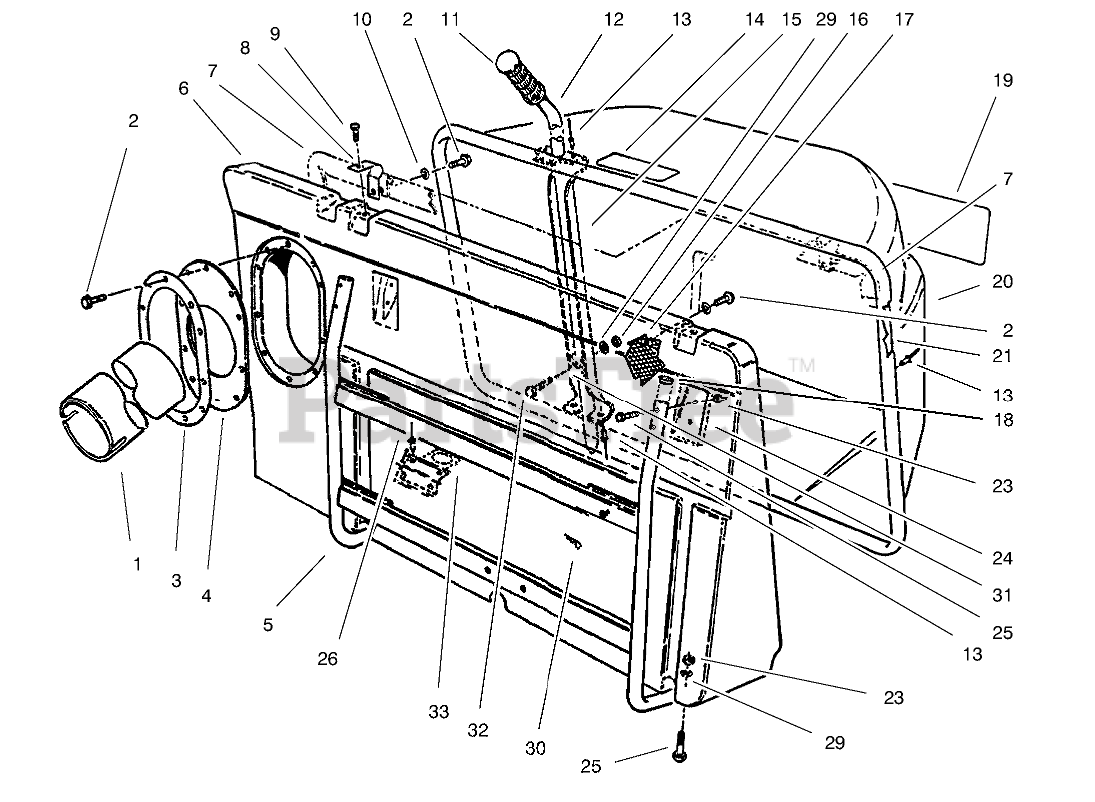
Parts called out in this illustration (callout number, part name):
1	DUCT-BAGGER
2	SCREW-HWHTF
3	RING-RETAINING
4	RING-RETAINER, RUBBER
5	Frame
6	BAG-FRONT
7	SEAL-BAG
8	Bracket-Hinge
9	SCREW-HH
10	WASHER-FLAT
11	GRIP-HANDLE
12	HANDLE-DUMP
13	RIVET-POP
14	DECAL - WARNING
15	Channel-Dump Handle
16	NUT-LOCK, NI
17	Screen Bag
19	DECAL-BAG, EASY EMPTY
20	BASKET-GRASS
21	Frame-Grass Basket
23	NUT-LOCK, NI
24	Plate-Backup
25	SCREW-HH
26	RIVET-BLIND
29	WASHER-FLAT
30	PIN-HAIR
31	GUIDE-HANDLE, DUMP
32	SCREW-HH
33	Latch
